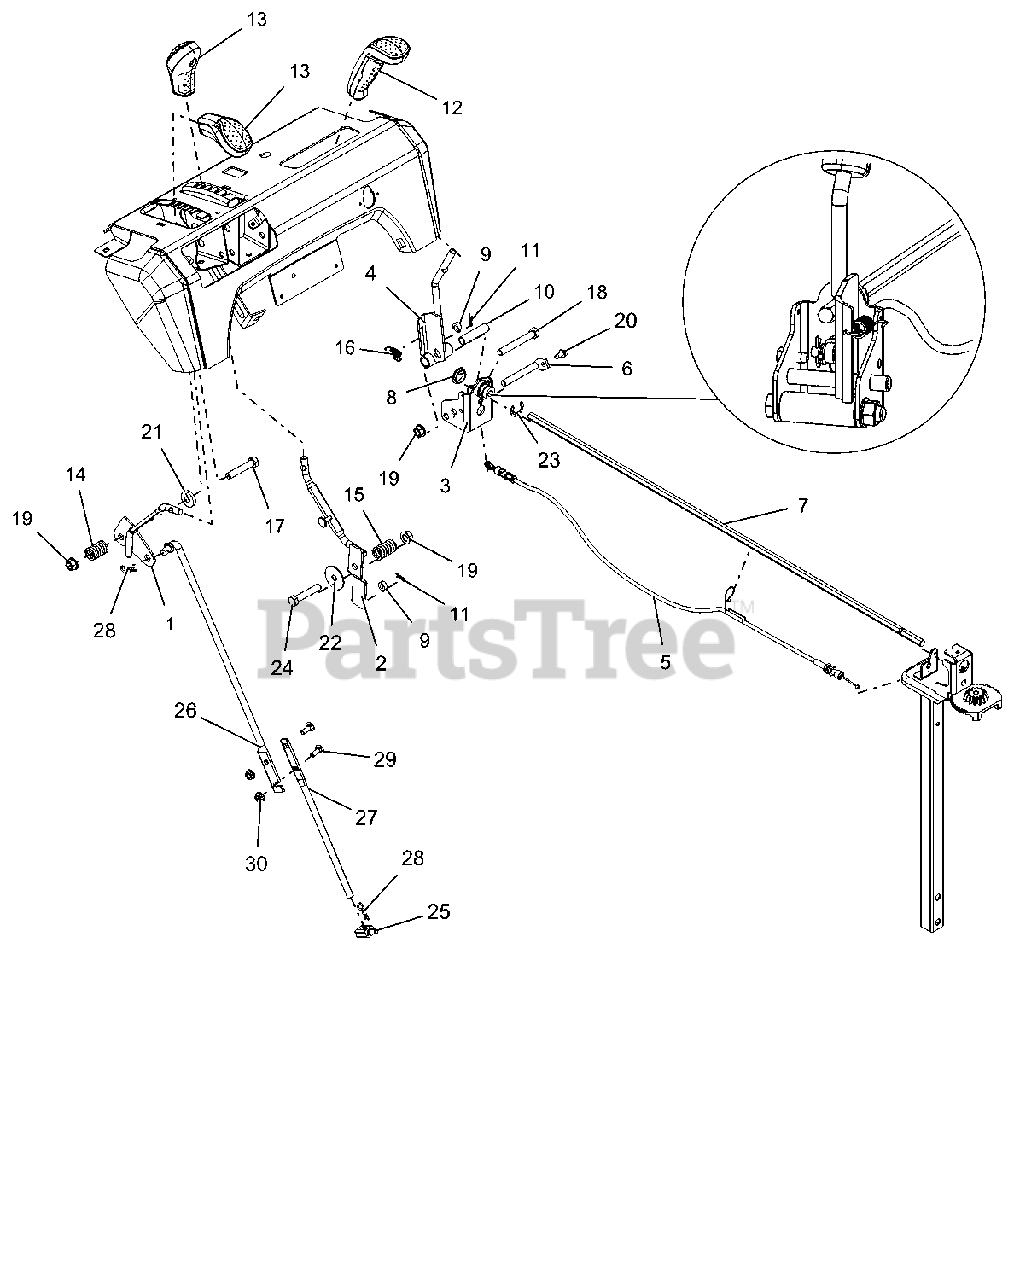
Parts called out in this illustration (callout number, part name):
1	WELDMENT,LG DASH SPEED CONTROL
2	WELDMENT,LG DASH DEFL CONTROL
3	WELDMENT-CONTROL BRACKET-CHUTE
4	WELDMENT,LG DASH QT CONTROL
5	CABLE, CHUTE LOCK, PRO
6	ROD, PIVOT - INTERLOCK
7	ROD, HEX - CHUTE ROTATION
8	BUSHING, POLYLINER-.75 SNAPIN
9	BSHG-SLV .265X.500X.219
10	SPCR, WHEEL .385X.500X2.00
11	PIN-HAIR INT .06X.18X.77
12	HANDLE, QUICK TURN, ASM
13	KNOB, CONTROL, DASH
14	SG-COMP .125X.781X1.250
15	SG-COMP .125X.781X1.250
16	SPRING-EXT .047X.438X1.45
17	@BLT-HEX .31-18X2.25 GR5 YWZC
18	@BLT-HEX .38-16X2.75 GR5 YWZC
19	@NUT-LK-TOP-FLG .38-16 YWZC
20	SCR-TAP .25-20X.50 HWH TR YWZ
21	WSHR-FL-STL .630X1.005X.062 YZ
22	WSHR-FL-STL .380X1.50X.062 YWZ
23	E-RING .750X.050
24	@BLT-HEX .38-16X2.00 GR5 YWZC
25	PIVOT,SHIFT ROD .375-16(TRUNN)
26	ROD, SHIFT - UPPER
27	ROD, SHIFT - LOWER
28	PIN-HAIR INT .08X.18X1.18 YWZC
29	@BLT-RDHDSQNK .25-20X.75 G5YZ
30	@NUT-LK-CTR-FLG .25-20 YWZC
